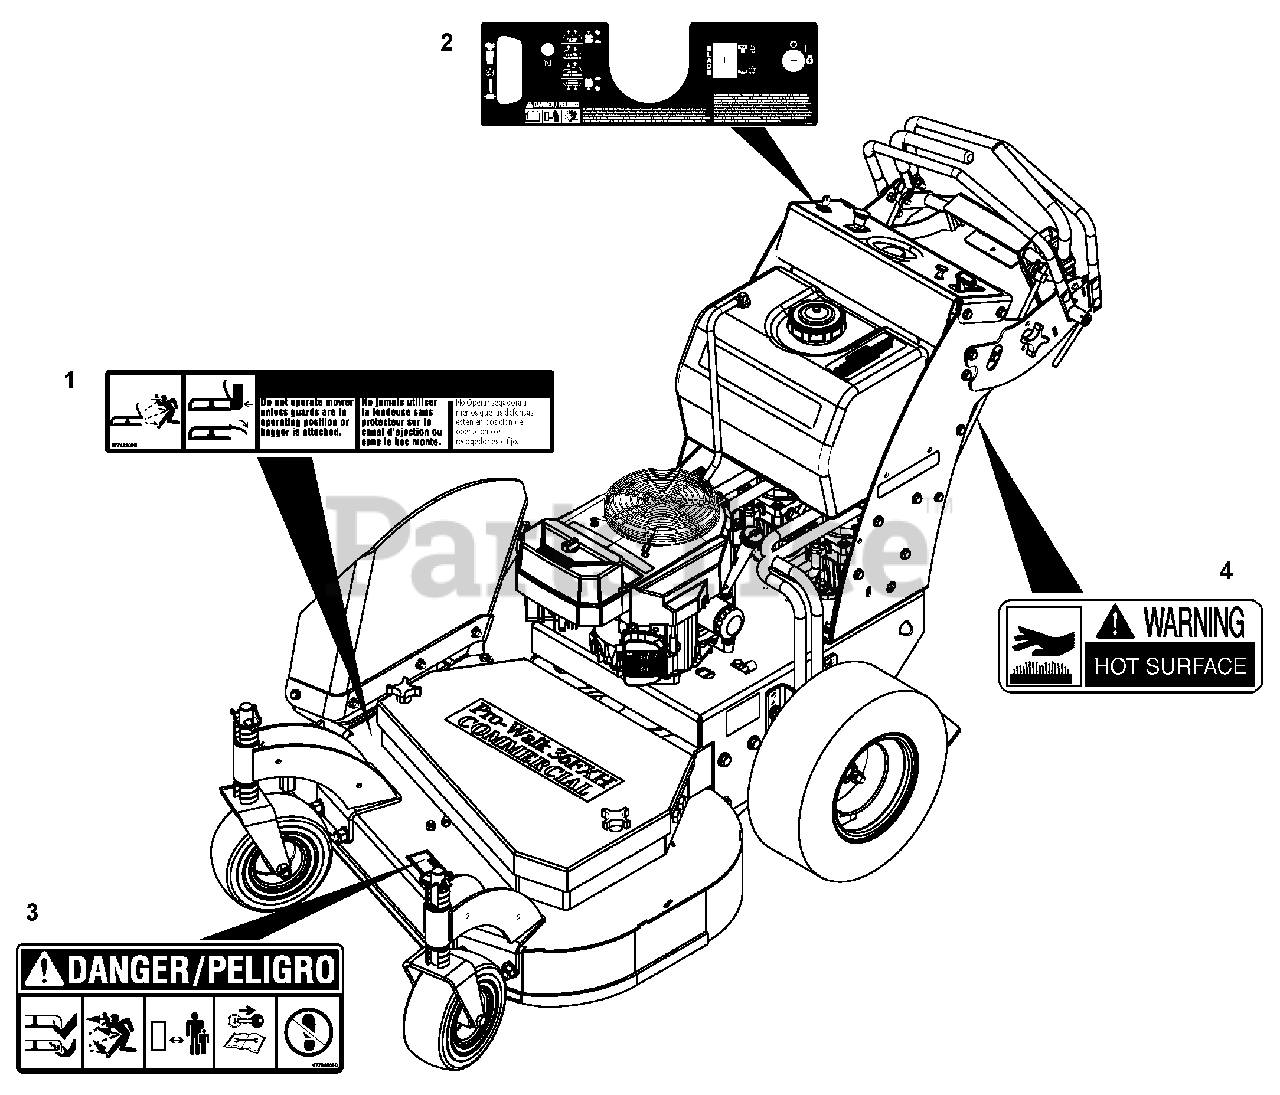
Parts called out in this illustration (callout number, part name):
1	Decal, Warning
2	Decal, Console
3	Decal, Mower Pan Danger
4	Decal, Danger Hot Surfaces
